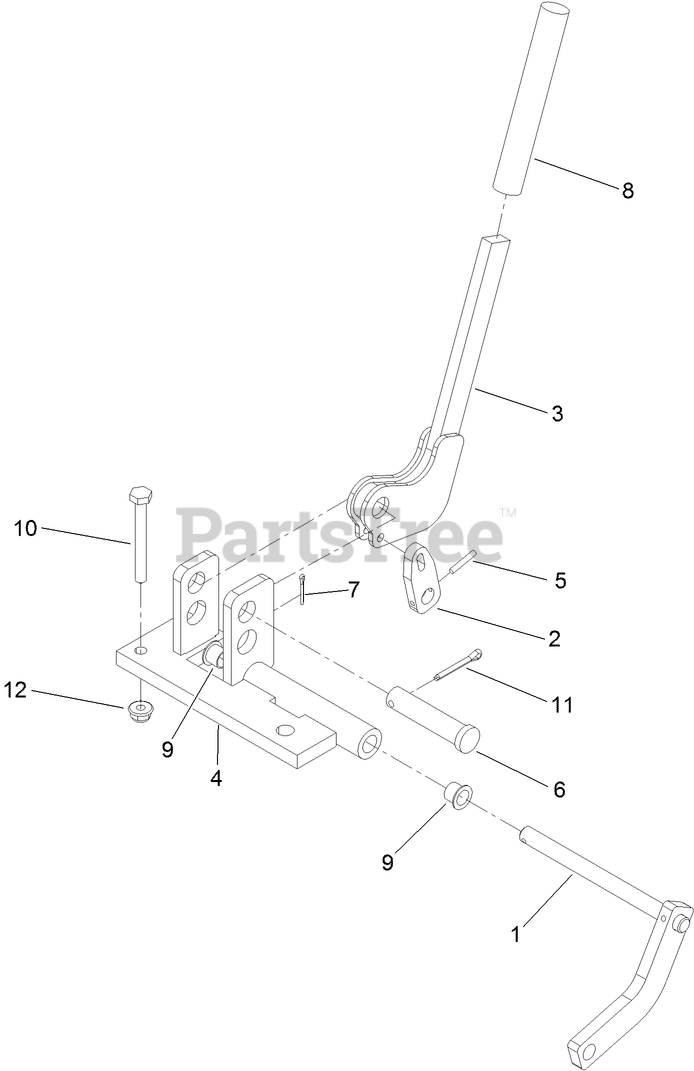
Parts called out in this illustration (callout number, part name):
2	PLATE-LEVER, FOOT CONTROL
3	LEVER-CONTROL, VALVE
4	GUIDE-SHAFT
6	PIN-CLEVIS
7	PIN-COTTER
8	GRIP-HANDLE
9	BEARING
10	SCREW-HH
11	PIN-COTTER
12	NUT-HF
